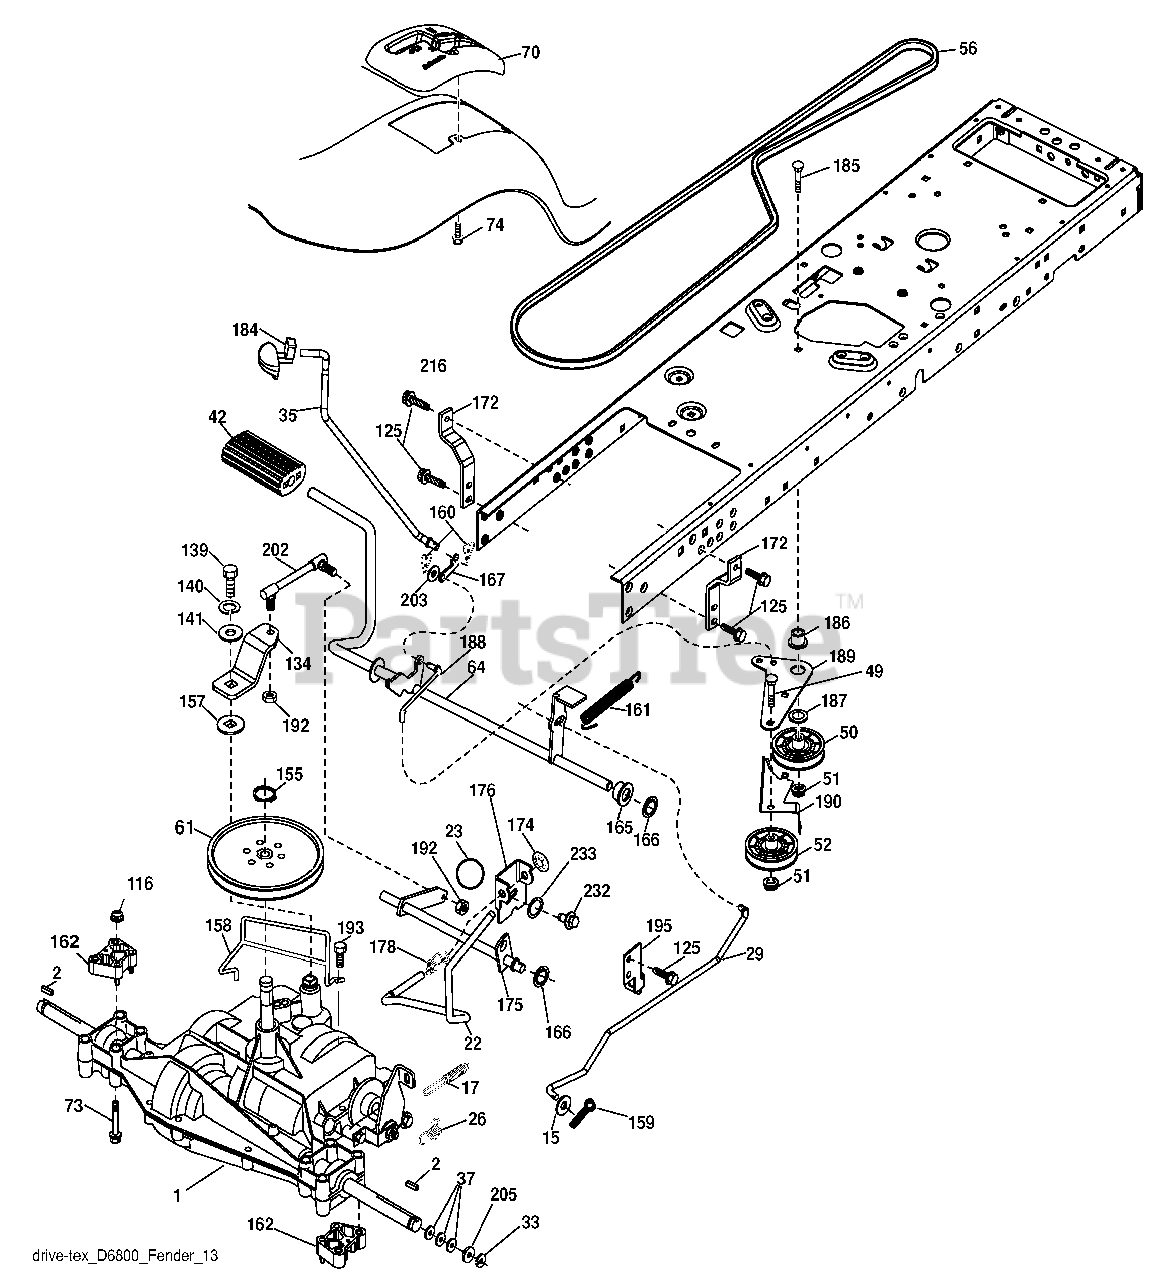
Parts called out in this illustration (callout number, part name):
1	Transaxle, D6800 (See Transaxle Breakdown)
2	Key Square
15	Washer 13/32 x 13/16 x 16 Ga.
17	Spring, Brake
22	Rod Shift
23	Knob
26	Spring Brake RTN
29	Rod, Brake
33	Ring E
35	Rod, Brake, Park
37	Washer 25/32 x 1-1/4 x 16 Ga.
42	Cover, Foot Pedal
49	Bolt
50	Pulley Idler Flat
51	Lock Nut 3/8-16
52	Idler V-Groove
56	V-Belt, Drive
61	Pulley Transaxle
64	Shaft Asm. Pedal Brake Control
70	Console
73	Bolt Hex FLNGD 5/16 - 18 x 3.75
74	Screw 1/4 x 1/2
116	Nut Lock Hex Flange 5/16-18
125	Screw 5/16-18 x 3/4
134	Arm Shift
139	Bolt 1/4-20 unf Gr. 8 w/Patch
140	Washer Lock Hvy Helical 1/4
141	Washer 9/32 x 3/4 x 10 Ga.
155	Ring Retainer
157	Washer Plate Shf
158	Keeper T/A
159	Pin Cotter 1/8 x 3/4
160	Retainer Clip
161	Spring, Return, Clutch
162	Spacer
165	Busing Shaft Brake Hand Control
166	Nut Push .625
167	Latch Brake Parking
172	Strap Torque LH
174	Nut Push
175	Shaft Asm Shift
176	Arm Clevis Rod Shift
178	Spring Shift
184	Handle Parking Brake
185	Bolt
186	Spacer Retainer
187	Washer
188	Link Clutch Ground Drive
189	Bellcrank Ground Drive
190	Keeper Bellcrank Ground Drive
192	Nut Lock Center 1/4-28
193	Screw 5/16-18 x 3/4
195	Bracket Brake Rod
202	Link Shift
203	Washer 11/32 x 11/16 x 16 Ga.
205	Washer 25/32 x 1-5/8 x 16 Ga.
232	Bolt 7/16-14 x 1 Gr.5
233	Washer Serrated
